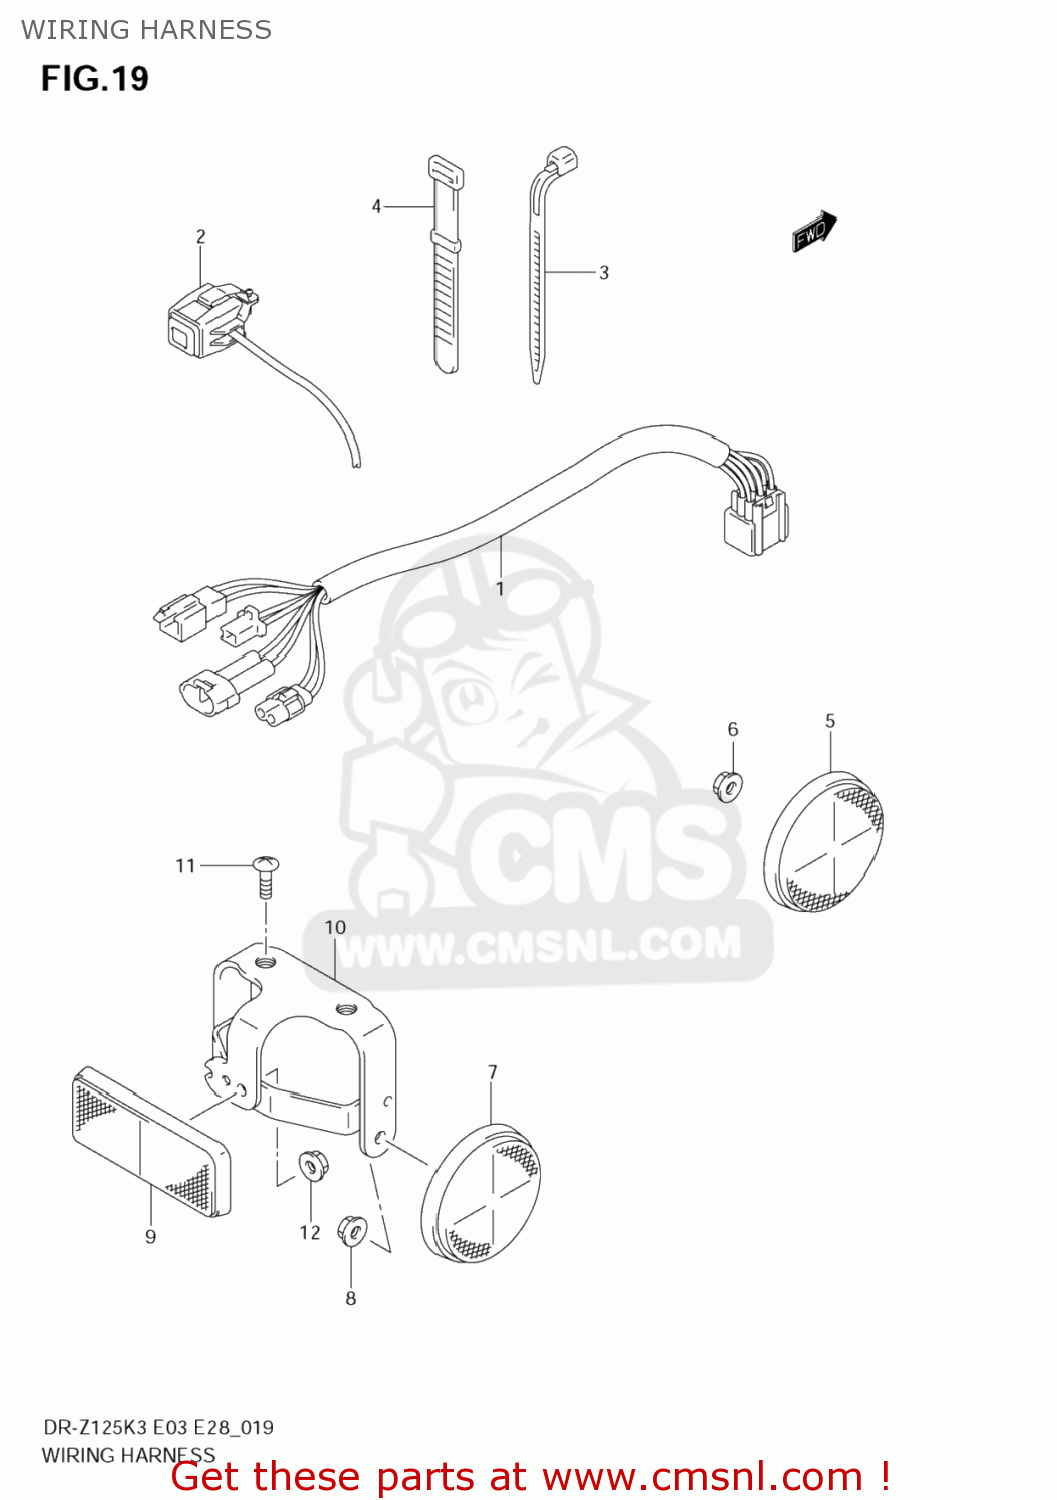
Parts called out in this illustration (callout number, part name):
1	HARNESS,WIRING
2	SWITCH ASSY,ENGINE STOP
3	CLAMP(L:165)
4	CLAMP(L:120)
5	REFLECTOR,REFLEX FR
6	NUT
7	REFLEX REFLECTOR,RR
8	NUT
9	REFLECTOR ASSEMBLY,REAR
10	BRACKET,SIDE & RR REFL
11	SCREW 6X12
12	NUT
